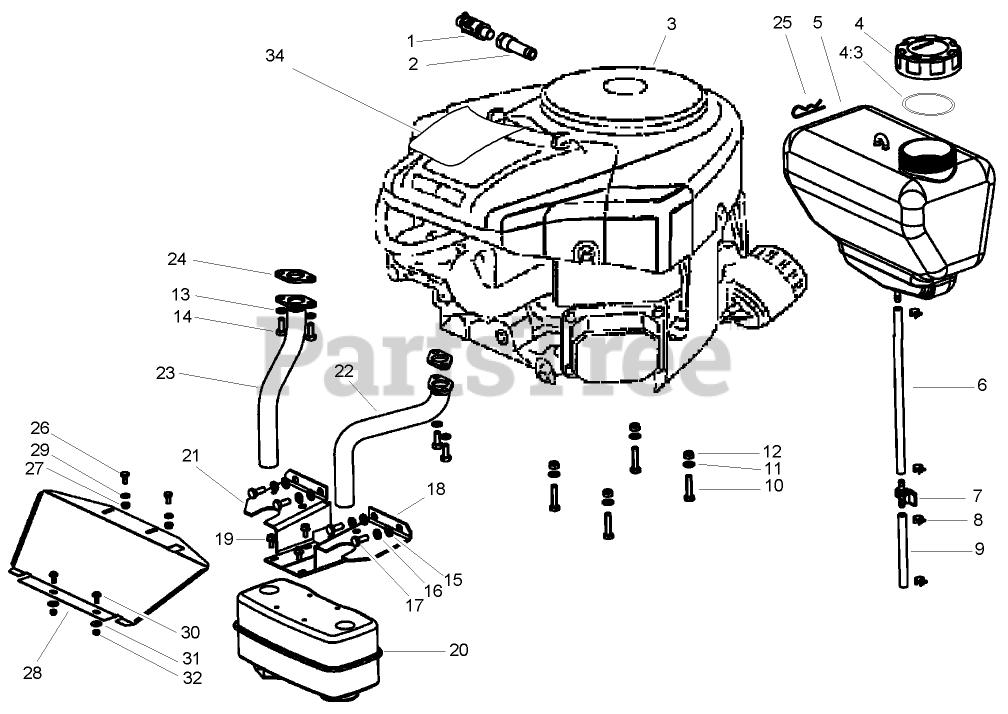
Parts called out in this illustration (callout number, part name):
1	VALVE-OIL DRAIN
2	Coupler-Oil Drain
3	Loose Parts Package
4	GAS CAP ASM
4:3	GASKET-CAP, GAS
5	TANK-FUEL
6	LINE-FUEL
7	VALVE-TANK, FUEL
8	CLAMP-LINE, FUEL
9	LINE-FUEL
10	SCREW-HH
11	WASHER-PLAIN
12	NUT-LOCK, NI
13	WASHER-SPRING
14	SCREW-HH
15	WASHER-PLAIN
16	WASHER-SPRING
17	SCREW-HH
18	GUARD-MUFFLER, LH
20	MUFFLER
21	GUARD-MUFFLER, RH
22	TUBE-EXHAUST, LH
23	TUBE-EXHAUST, RH
24	GASKET-EXHAUST
25	PIN-HAIR
26	SCREW-HH
27	NUT-LOCK
28	SHIELD-HEAT
29	WASHER-FLAT
31	WASHER-FLAT
32	NUT-LOCK
